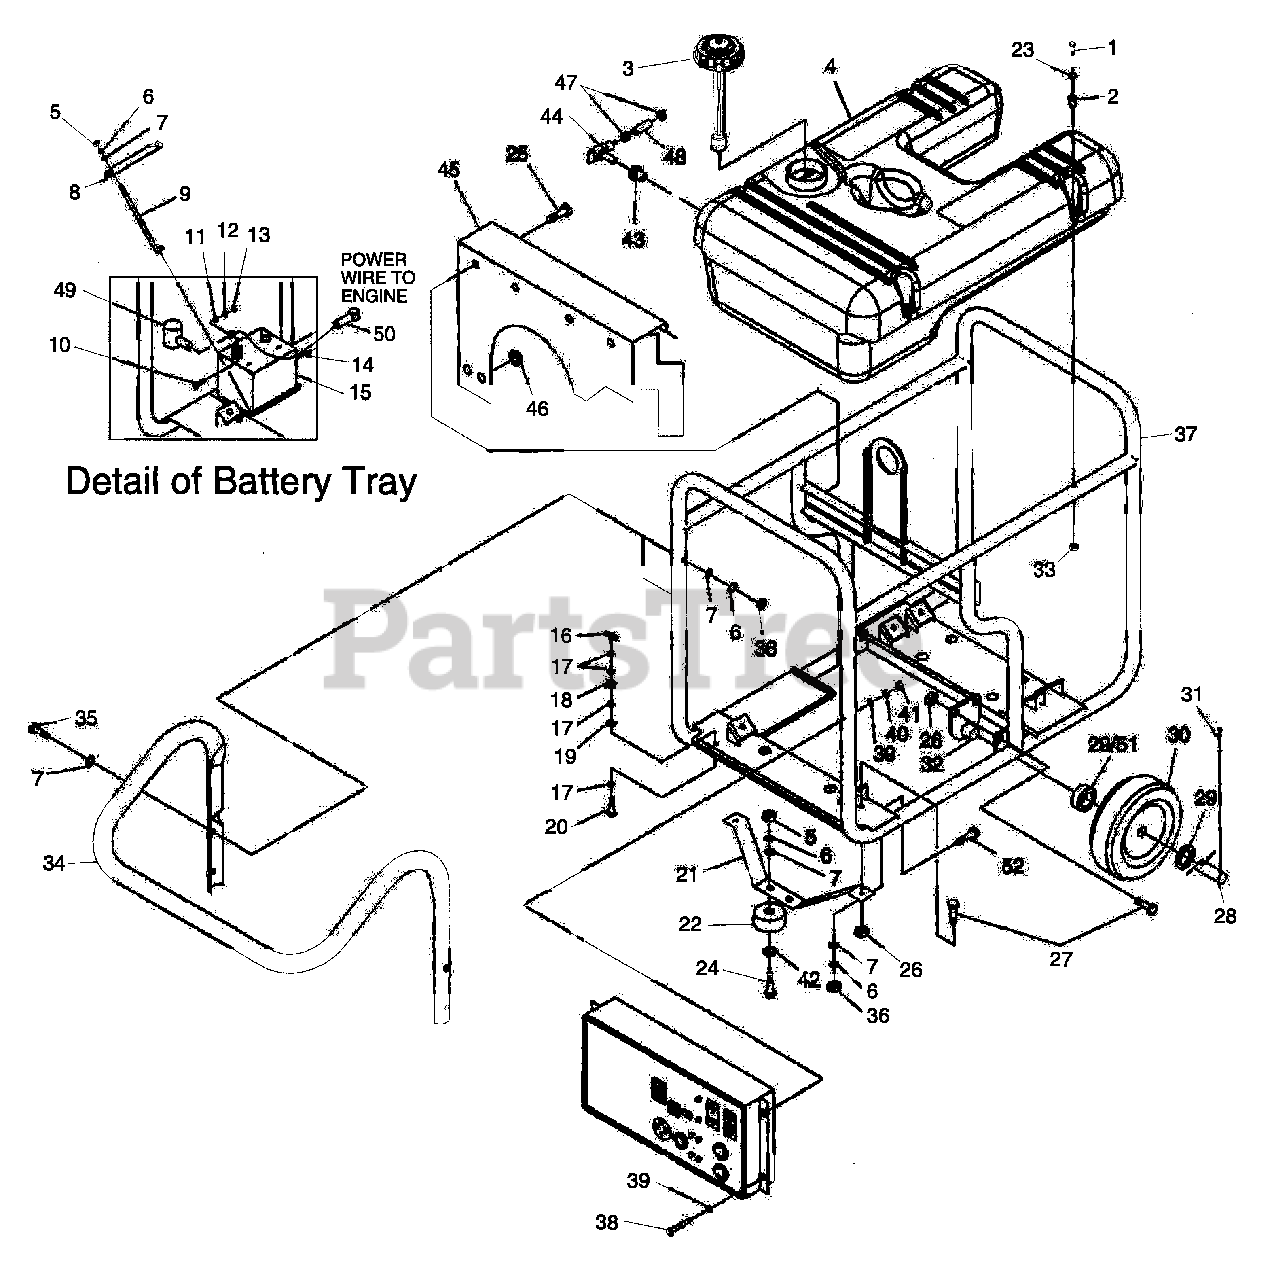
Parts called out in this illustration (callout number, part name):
1	SCREW HHC M6-1.0X55
2	RUBBER TANK MOUNT
3	CAP, FUEL WITH GAUGE & VENT
4	KIT, FUEL TANK
5	NUT HEX M8-1.25
6	WASHER LOCK M8-5/16
7	WASHER FLAT 5/16
8	BRACKET BATTERY
9	BOLT, BATTERY J-BOLT
10	SCREW HHC 1/4-20 X 3/4 G5
11	WASHER FLAT 1/4
12	WASHER LOCK M6-1/4
13	NUT HEX 1/4-20
14	BATTERY CABLE, RED
15	BATTERY U1
16	NUT WING 5/16-18 BRASS
17	WASHER FLAT 5/16 BRASS
18	NUT HEX 5/16-18 BRASS
19	5/16 SPECIAL L/WASH
20	SCREW HHC 5/16-18X1.5 BRASS
21	BRACKET FRONT FOOT (15 kW)
22	VIB MOUNT
23	WASHER FLAT .25ID X 1"OD
24	SCREW HHC M8-1.25 X 30
25	SCREW HHTT M6-1.0X 12
26	NUT LOCK FL 3/8-16
27	BOLT CARR 3/8-16 X 1
28	AXLE, 3/4"DIA X 30" (15 kW)
29	WASHER FLAT 3/4" (15 kW)
30	12.3" PNEUM WHEEL 3/4" AXLE (15 kW)
31	PIN COTTER 1/8 X 1-1/4
32	BRACKET, WHEEL SPACER
33	NUT FLANGE M6-1.0 NYLOK
35	SCREW HHC 5/16-18 X 2-1/2 G5
36	NUT LOCK HEX 5/16-18 NYLON INSERT
37	FRAME
38	SCREW HHC M5-0.8 X 45 G8.8
39	WASHER FLAT M5
40	WASHER LOCK M5
41	NUT HEX M5-0.8
42	WASHER FLAT 1"
43	BUSHING TANK DEXTOR
44	VALVE, PLASTIC TANK
45	AIR DEFLECTOR
46	GROMMET .75 X .06 X .50
47	CLAMP HOSE BAND 1/4
48	HOSE 1/4 ID
49	BOOT BATTERY CABLE
50	BOOT STARTER CABLE
51	SPACER, AXLE (15 kW)
52	SCREW HHC 5/16"-18 X 1"
